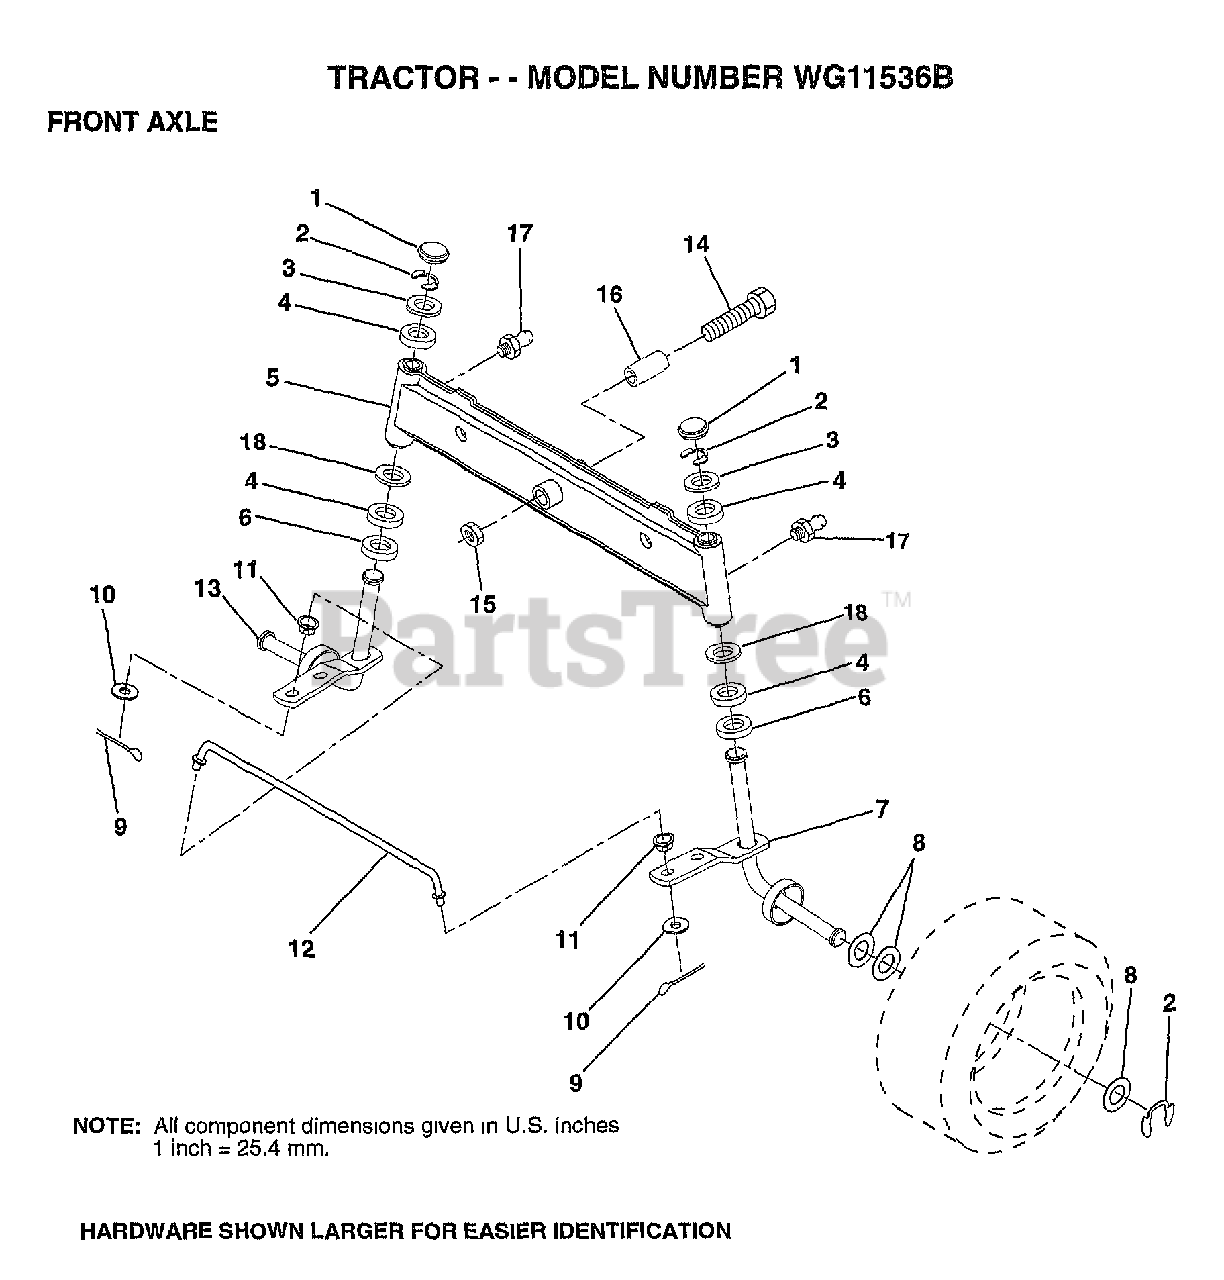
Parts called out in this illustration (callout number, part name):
1	CAP
2	RING
3	WASHER
4	COL. SRTG. BEAR.
5	AXLE ASM FRONT
6	WASHER .T
7	SPINDLE.ASSY.RH
9	COTTER PIN
10	WASHER
11	BUSHING.DRAGLINK
12	TIE ROD
13	SPINDLE.ASSY.LH
14	BOLT HEX 5/8-11
15	"NUT-LOC,FLANGE LT"
16	BEARING
17	ZERK M
18	WASHER
